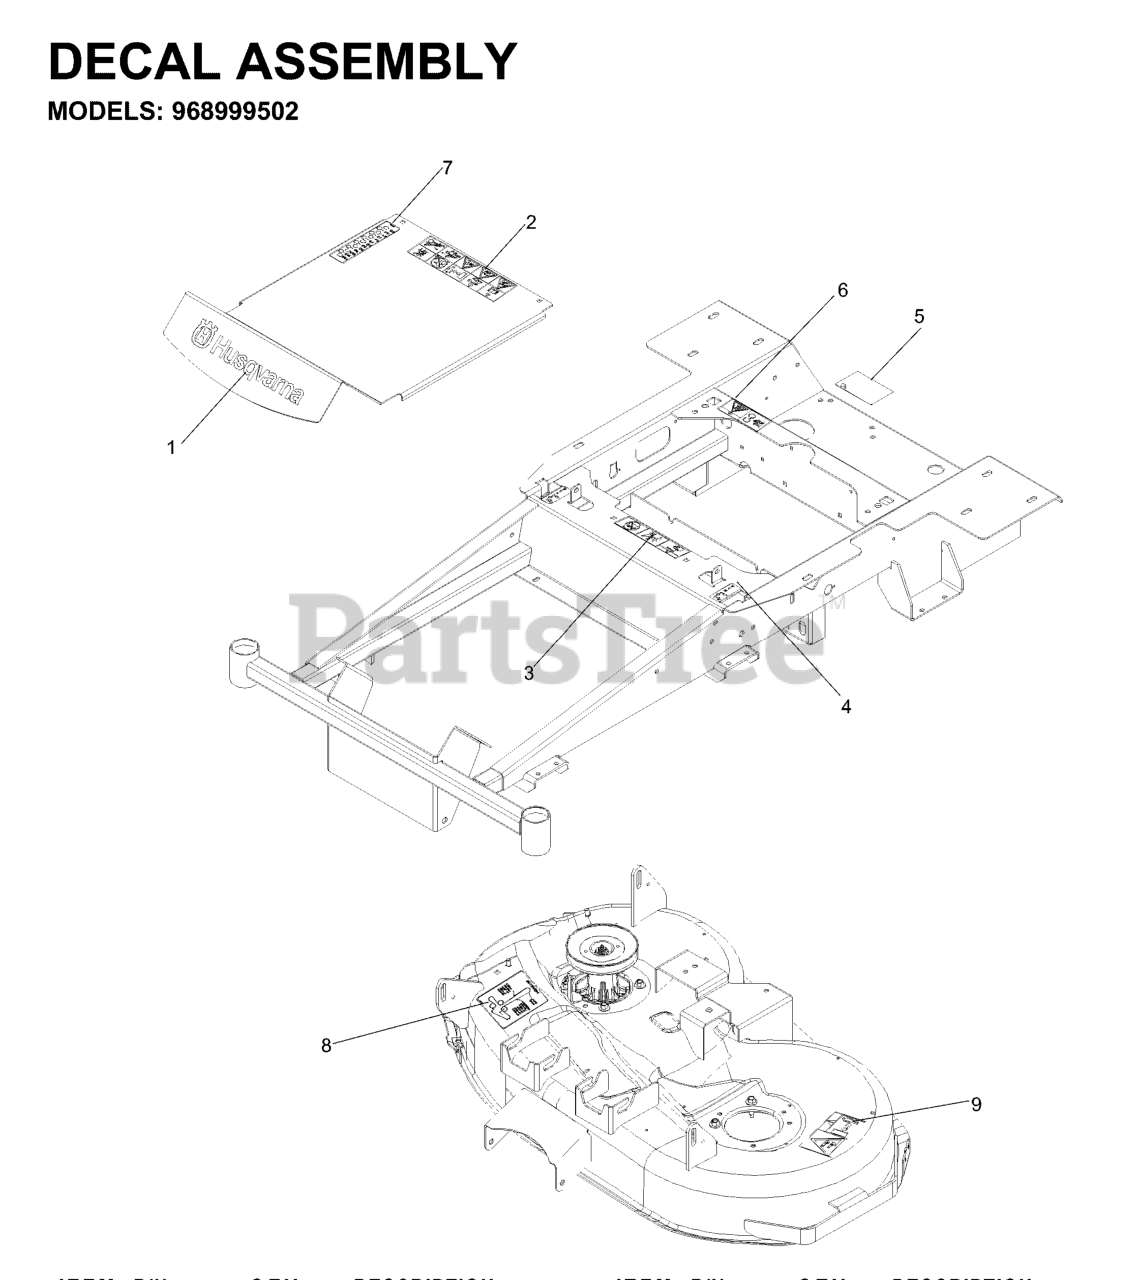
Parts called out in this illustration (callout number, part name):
1	DECAL, HUSQ 12" BLUE
2	DECAL, WARNING
3	EURO DECAL-BATTERY WARNIN6
4	DECAL, MOTION CONTROL
5	DECAL, DO NOT TOW
6	DECAL, BELT DRIVE
7	DECAL, HEIGHT, EZ
8	DECAL, BELT ROUTING
9	DECAL, EURO SEVERING
10	DECAL, EZ17
